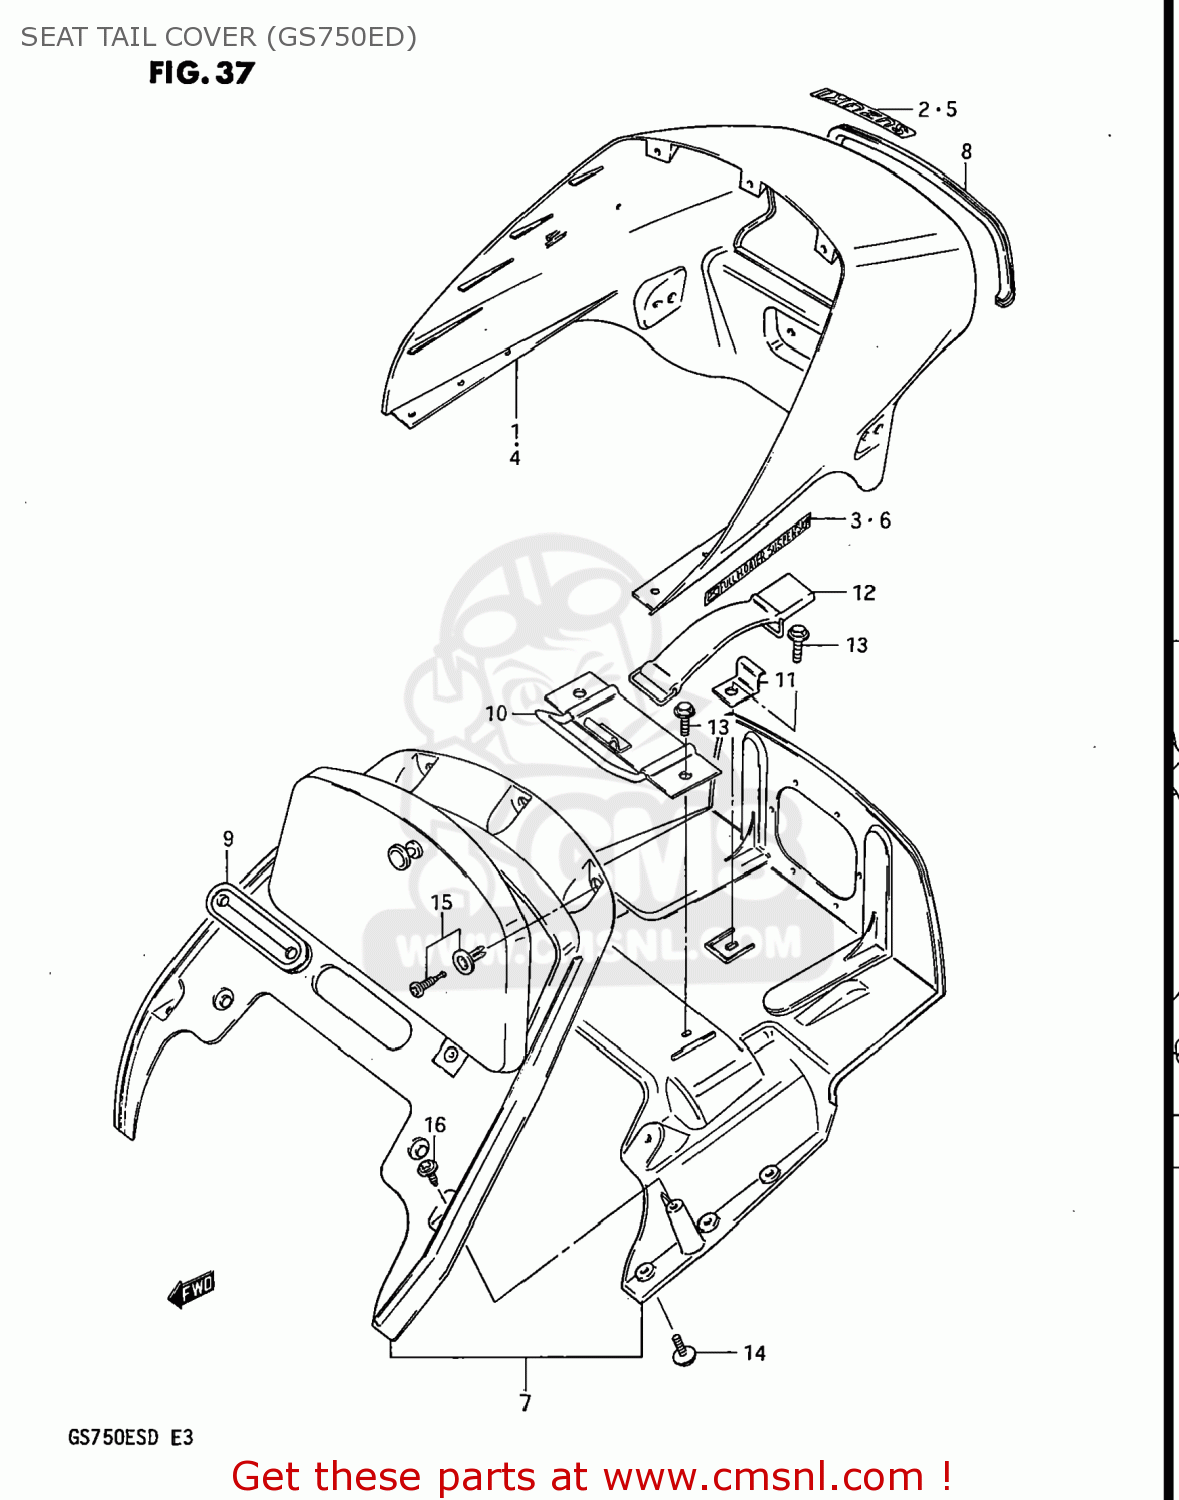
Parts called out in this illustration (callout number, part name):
1	COVER COMP,SEAT TAIL
2	EMBLEM
3	EMBLEM
4	COVER COMP,SEAT TAIL
5	EMBLEM
6	EMBLEM
7	FLAP,SEAT TAIL COVER
8	MOLDING,SEAT TAIL COVER
9	GROMMET,SEAT TAIL COVER
10	PLATE,CHAIN LOCK HOLDER
11	PLATE,SEAT HOOK
12	BAND
13	BOLT
14	SCREW
15	CLIP
16	SCREW
